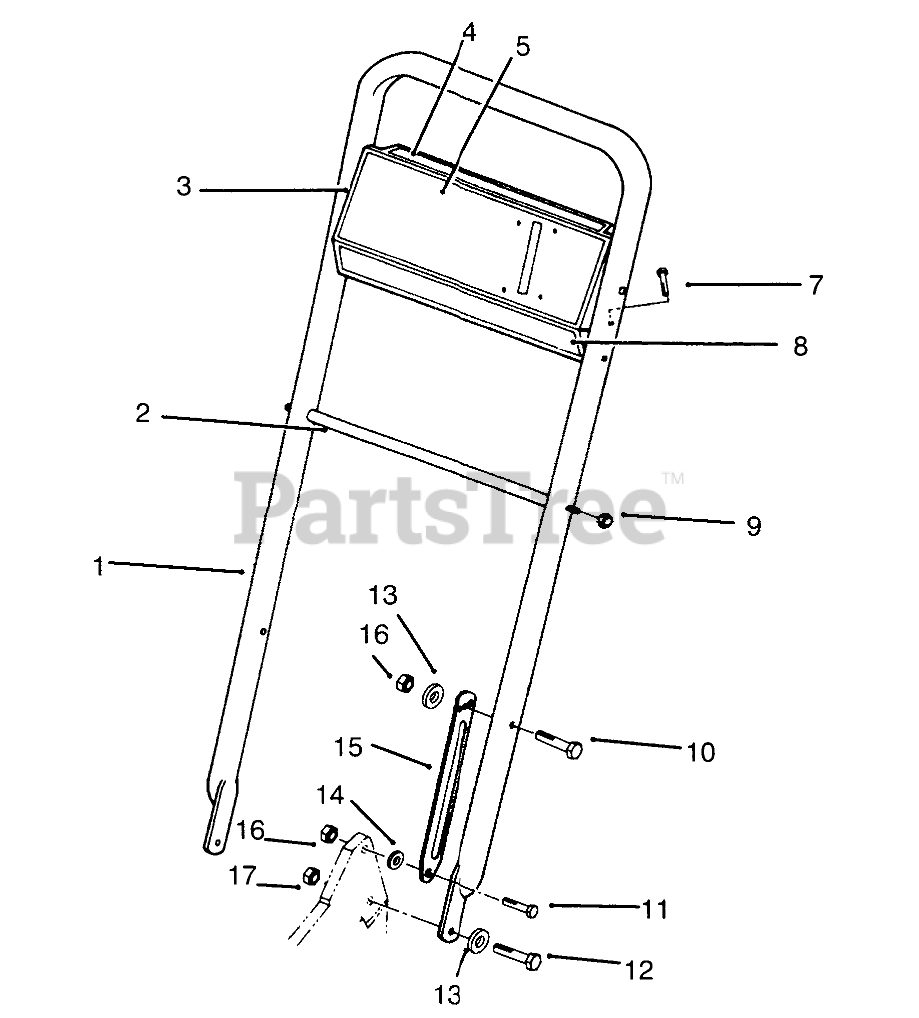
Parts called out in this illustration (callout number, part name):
1	Handle
2	ROD-SUPPORT, BAG
3	Panel-Control (Incl Ref. #4,5,8)
4	DECAL-PANEL, REAR
5	DECAL - PANEL
7	SCREW-HWHTF
8	DECAL-PANEL, PROLINE
9	NUT-CAP
10	SCREW-HH
11	SCREW-SHOULDER
12	SCREW-HH
13	WASHER-BELLEVILLE
14	SPACER
15	Latch-Handle
16	NUT-LOCK, NI
17	NUT-LOCK, NI
